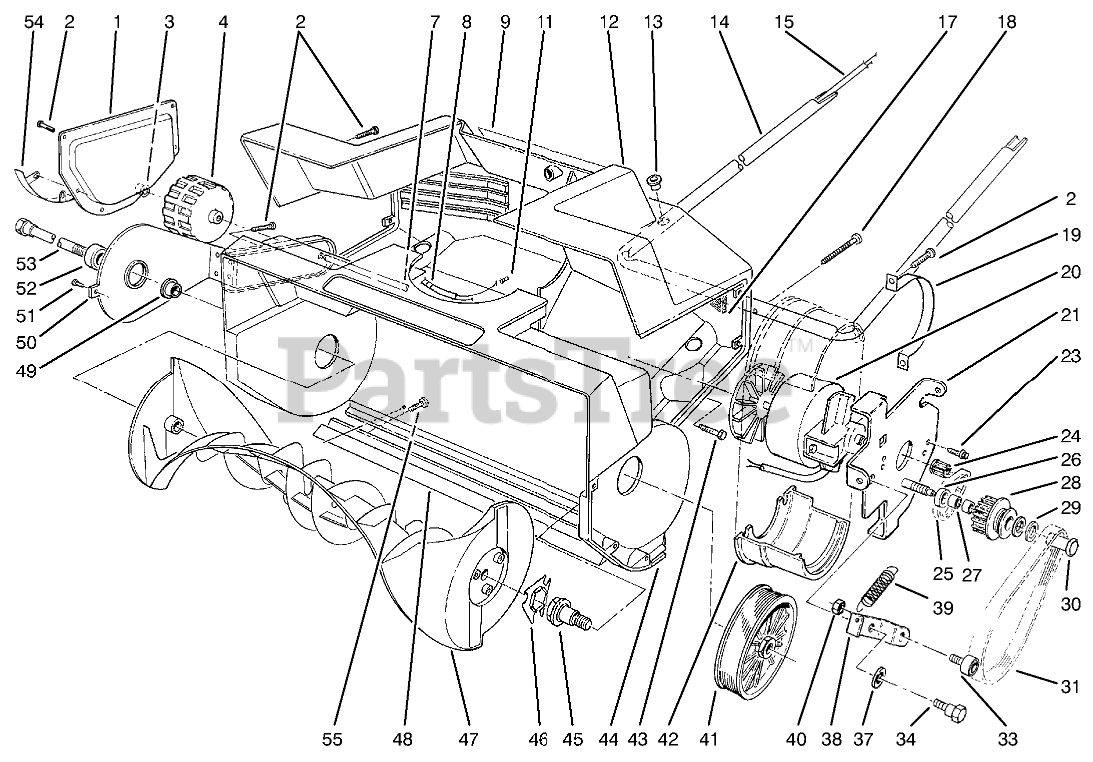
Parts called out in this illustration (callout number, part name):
1	Plate-Side
2	SCREW-PPH
3	PUSHNUT-CAP, WASHER
4	Wheel
7	Shaft-Axle
8	Relief-Strain
9	Decal-Danger
11	Connector
12	Shroud-Housing
13	BUSHING
14	Tube-Lower Handle
15	Wire Harness
17	Filter-Foam
18	Screw-Pan Head
19	Strap-Motor
20	Motor
21	Motor Plate ASM
23	Screw-Hex Washer Hd.
24	Pulley-Driver
25	BELT-PULLEY, IDLER/DRIVER
26	WASHER
27	Bearing-Needle
28	Pulley Assembly-Idler (Incl. Ref. #27)
29	WASHER-THRUST
30	Bolt-Idler
31	Belt-Drive
33	Bearing Assembly (Incl. Ref. #40)
34	SCREW-SHOULDER
37	WASHER
38	Bracket-Idler
39	Spring
40	NUT-LOCK, NI
41	Pulley-Driven
42	Clamp-Motor Bracket
43	SCREW-HH
44	Housing-Rotor
45	Shaft-Driver, Rotor
46	Coupler-Rotor
47	Rotor
48	Scraper
49	BUSHING
50	Bracket-Wheel (Incl. Ref. #52)
51	RIVET-POP
52	Bearing-Ball
53	Shaft-Rotor
54	Skid-Housing
55	Screw-Pan Head
